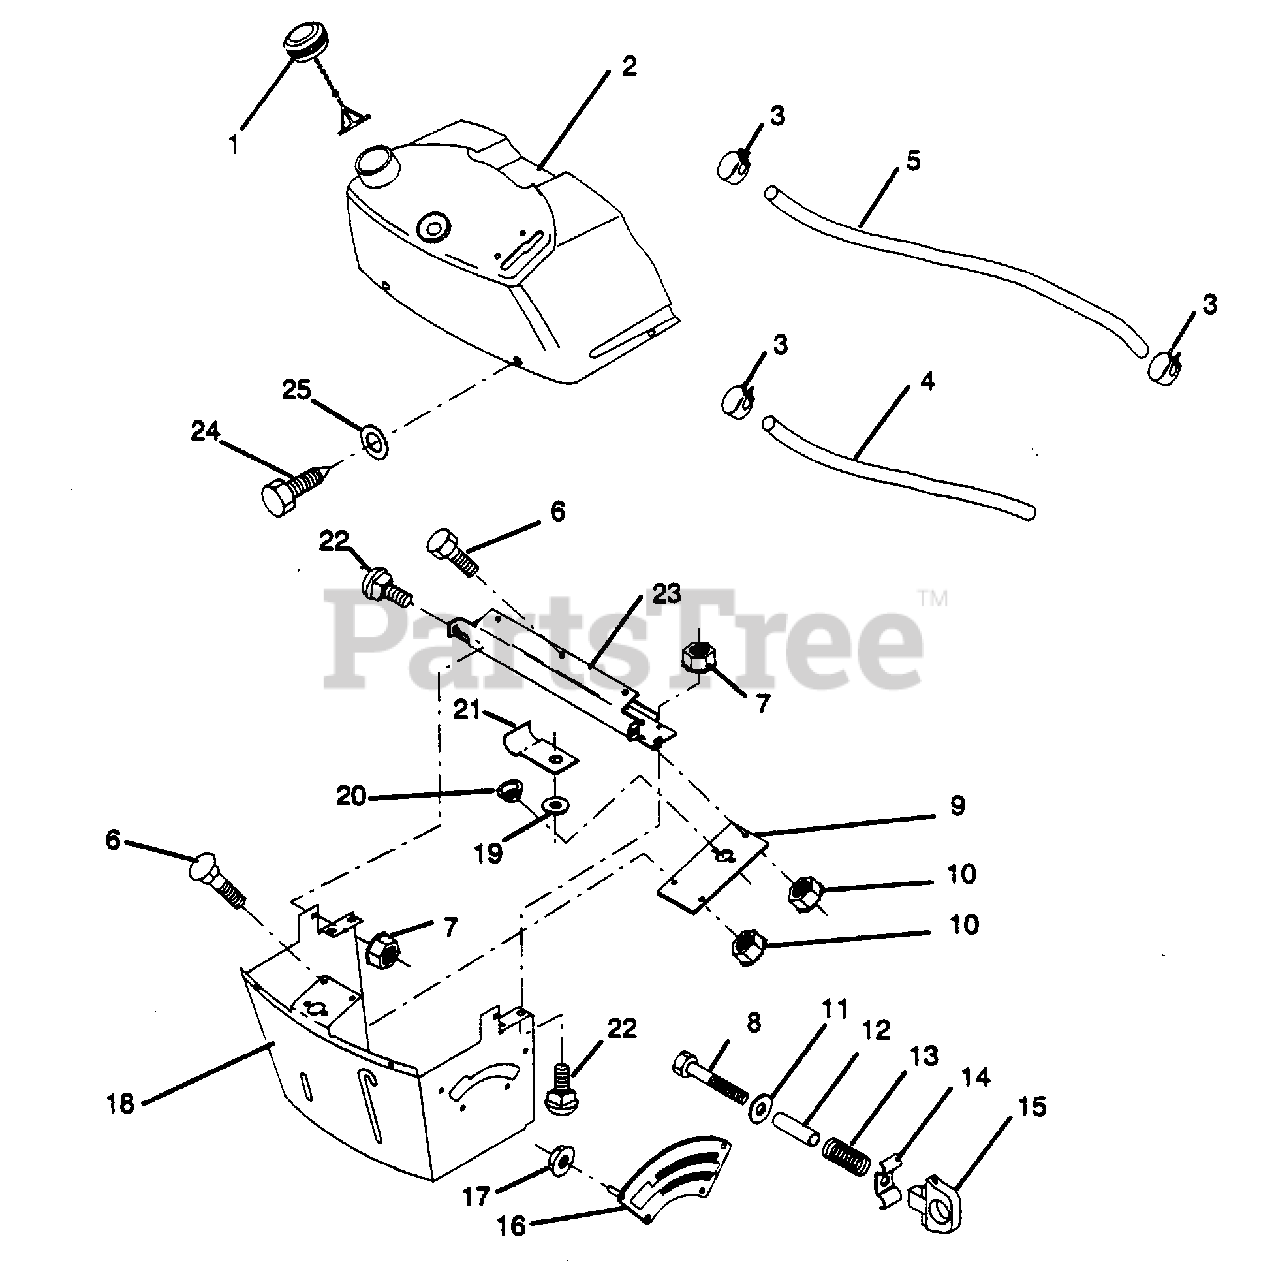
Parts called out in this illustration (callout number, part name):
1	Cap, Fuel (AYP part number)
2	Assembly, Dash & Fuel Tank (AYP part number)
3	Clamp, Hose (AYP part number)
4	Line, Fuel (AYP part number)
5	Line, Fuel (AYP part number)
6	Bolt, Hex, 1/4-20 x 3/4 (AYP part number)
7	Nut, Hex Keps 1/4-20 (AYP part number)
8	Bolt, Fin. Hex 1/4-20 x 1 1/2 (AYP part number)
9	Plate, Support (AYP part number)
10	Nut, Lock 1/4-20 (AYP part number)
11	Washer, 11/32 x 11/16 x 16 (AYP part number)
12	Spacer, Split (AYP part number)
13	Spring (AYP part number)
14	Knob, Height Retainer (AYP part number)
15	Knob, Height Stop (AYP part number)
16	Adjustment, Quadrant Height (AYP part number)
17	Nut, Self Thread 3/16-18 (AYP part number)
18	Support, Dash (AYP part number)
19	Washer 9/32 x 3/4 x 16 Ga. (AYP part number)
20	Grommet, Split (AYP part number)
21	Clip, Fuel line (AYP part number)
22	Bolt, Carriage 1/4-20 x 1/2 Gr.5 (AYP part number)
23	Brace, Cross (AYP part number)
24	Screw, Self Tapping 1/4-20 ??2 (AYP part number)
25	Washer 9/32x1/2 x 16 Ga. (AYP part number)
